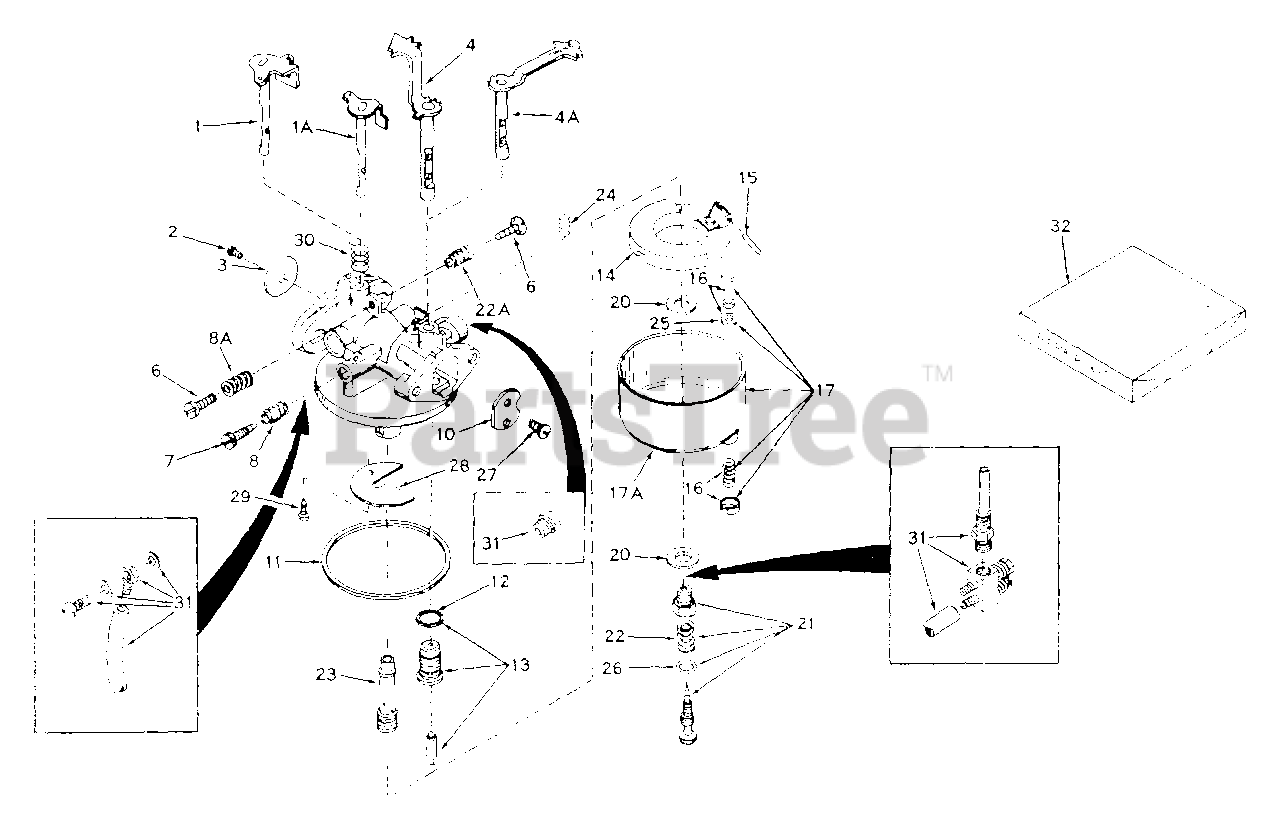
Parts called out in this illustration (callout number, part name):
1A	"Shaft & Lever Assy., Throttle
2	Screw, Sems, 6-32 x 3/16
3	Shutter, Throttle
6	Screw, Throttle adjusting
7	Needle, Idle adjusting
8	Spring, Adjusting needle
8A	Spring, Adjusting needle
11	Gasket, Bowl-to-body
17A	Bowl, Fuel
20	Gasket, Bowl-to-body
21	Needle Assy., Power adjusting
22	Spring, Adjusting needle
26	"O" Ring
32	Repair Kit
